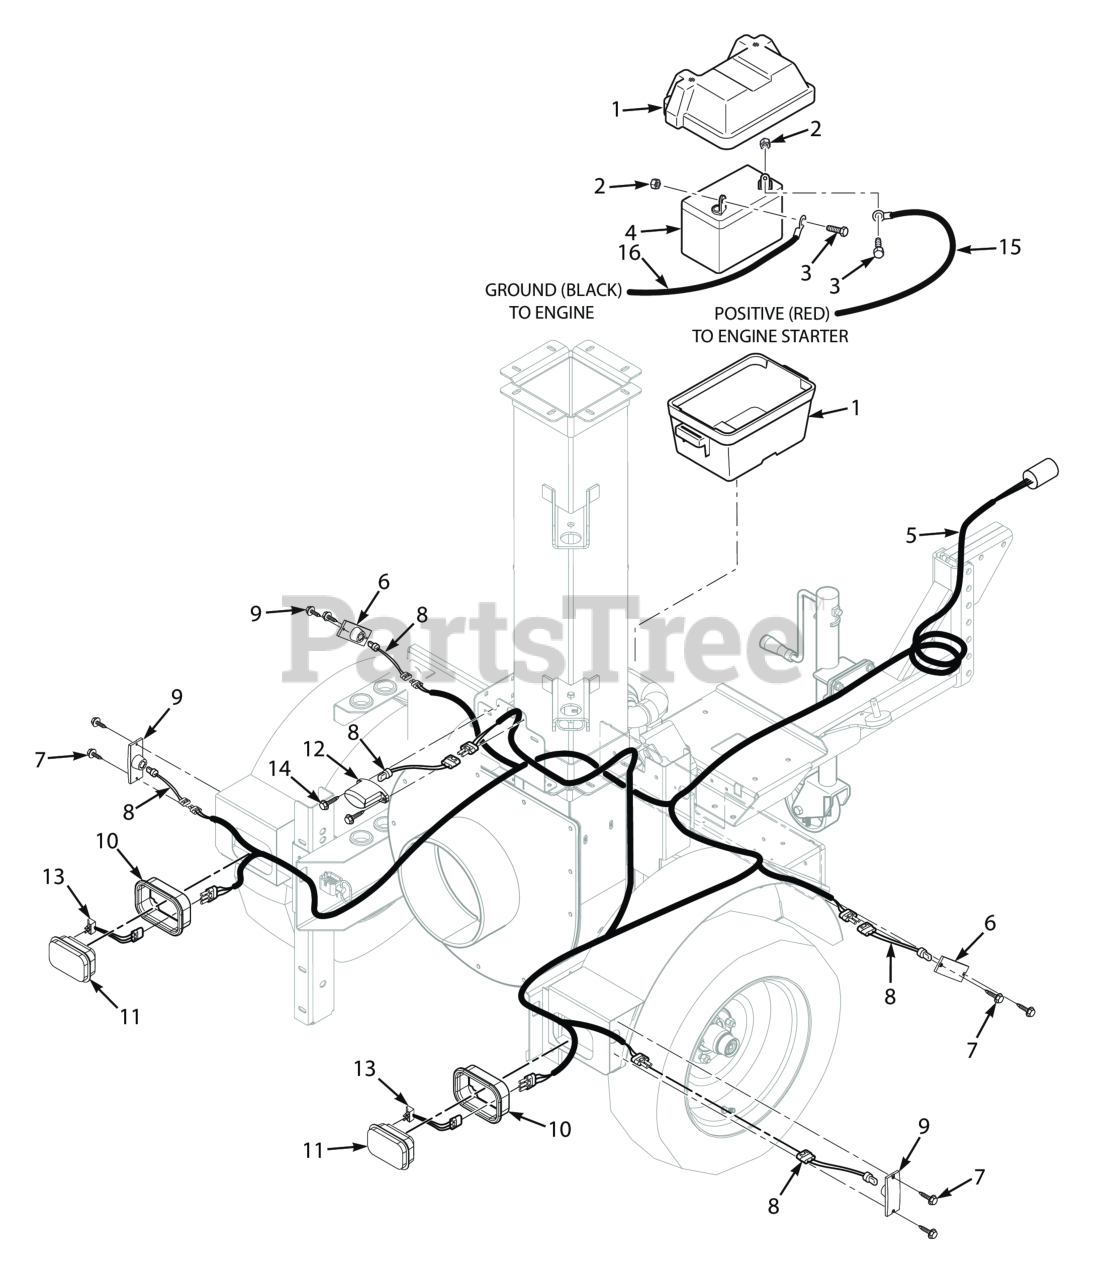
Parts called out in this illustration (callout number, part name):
1	Battery Box w/Strap
2	Nut, 1/4 - 20 Hex
3	BOLT, HEX HEAD, 1/4-20 X 5/8
4	Battery (not available through Scag Power Equipment)
5	Wire Harness, TL
6	Side Marker Light, Yellow (does not include #42)
7	Screw, #8-18 x 3/4" Self Tap
8	Pigtail, Side Marker Light
9	Side Marker Light, Red (does not include #42)
10	Grommet, Tail Light
11	Stop / Turn / Tail Light
12	Light, License Plate (includes #42)
13	Pigtail, Tail Light
14	SCREW, 10-32 X 3/4" SELF TAP
15	Battery Cable, Red 32" w/Conduit
16	Battery Cable, 27" Black (35BV & 37BV-EFI) - Briggs & Stratton
